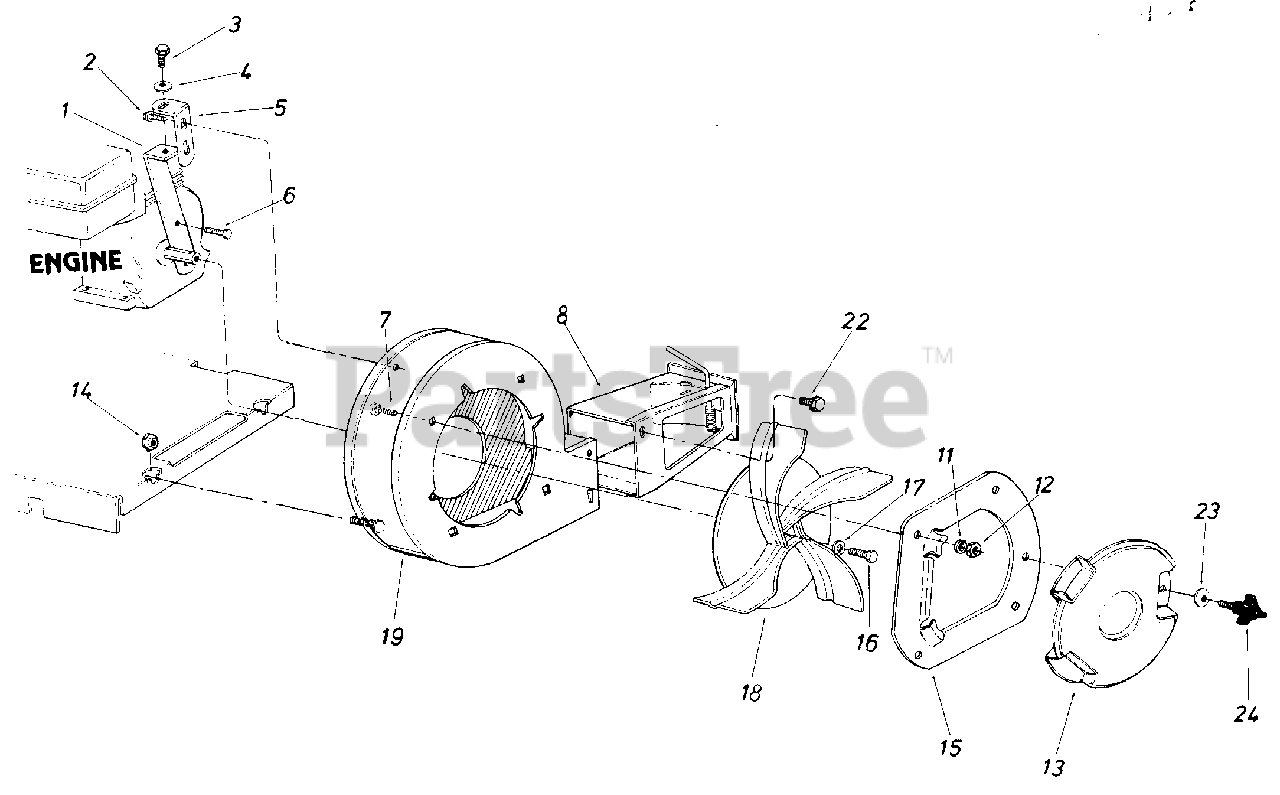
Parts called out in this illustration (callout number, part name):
3	HexBoit5/16-18 x .75" Lg.*
4	L.Wash. 5/16" I.D.*
7	Carriage Bolt 5/16-18 x .62" Lg. *
12	Hex Nut 5/16-18 Thd.*
13	Blower Guard
14	Hex Shoulder Nut .50" I.D.
15	Nozzle Plate Ass'y.
16	Hex Bolt 3/8-24 x 1.25" Lg.*
17	L.Wash. 3/8" I.D. HD.
18	Air Vane Plate Ass'y.
19	Blower Housing Ass'y. - Comp.
22	Hex Sems Bolt 5/16-18 x .62"
23	Belleville Wash. 34" I.D. x .87" O.D.
24	3-Arm Thumb Scr. 5/16-18 x .75" Lg.
